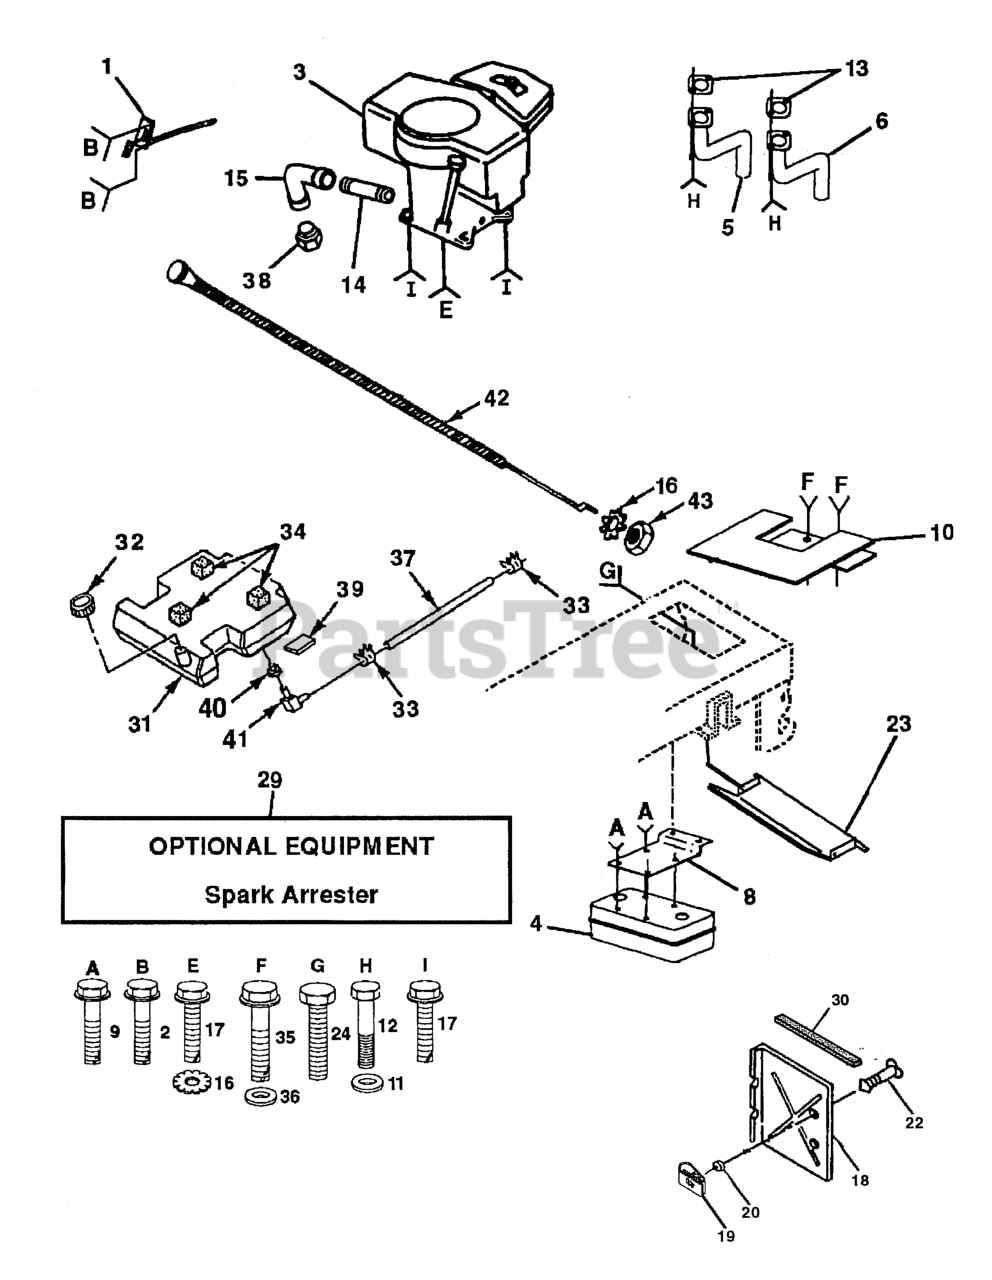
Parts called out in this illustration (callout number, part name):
1	THROTTLE CONTROL
2	SCREW LT
4	MUFFLER
5	MANIFOLD TUBE LH
6	MANIFOLD TUBE RH
8	BRACKET MUFFLER
9	SCREW ST
10	HEAT SHIELD
11	WASHER.LOCK.HVY.HLCL.SPR.5/16
12	Screw Hex Skt 5/16-18 unc x 3/4
13	Muffler Gasket
14	Nipple Pipe 3/8 Npt X 4-1/2"
15	ELBOW
16	LOCKWASHER
17	SCREW LT
18	HEAT SHIELD
19	RECEPTACLE LT
20	RETAINER LT
22	STUD 1/4 TURN
23	HEAT SHIELD
29	KIT.SPARK ARRESTOR 794945 B&S
30	FOAM-STRIP LT
31	FUEL TANK
32	FUEL CAP
33	HOSE CLAMP
34	PAD-SPACER LT
35	SCREW.THDROL.5/16-18X3/4.TTY
36	WASHER
37	FUEL LINE 54"
38	Plug Oil Drain
39	PAD IDLER TI
40	BUSHING OUTLET T
41	STEM FUEL TANK
42	CHOKE CONTROL
43	NUT
